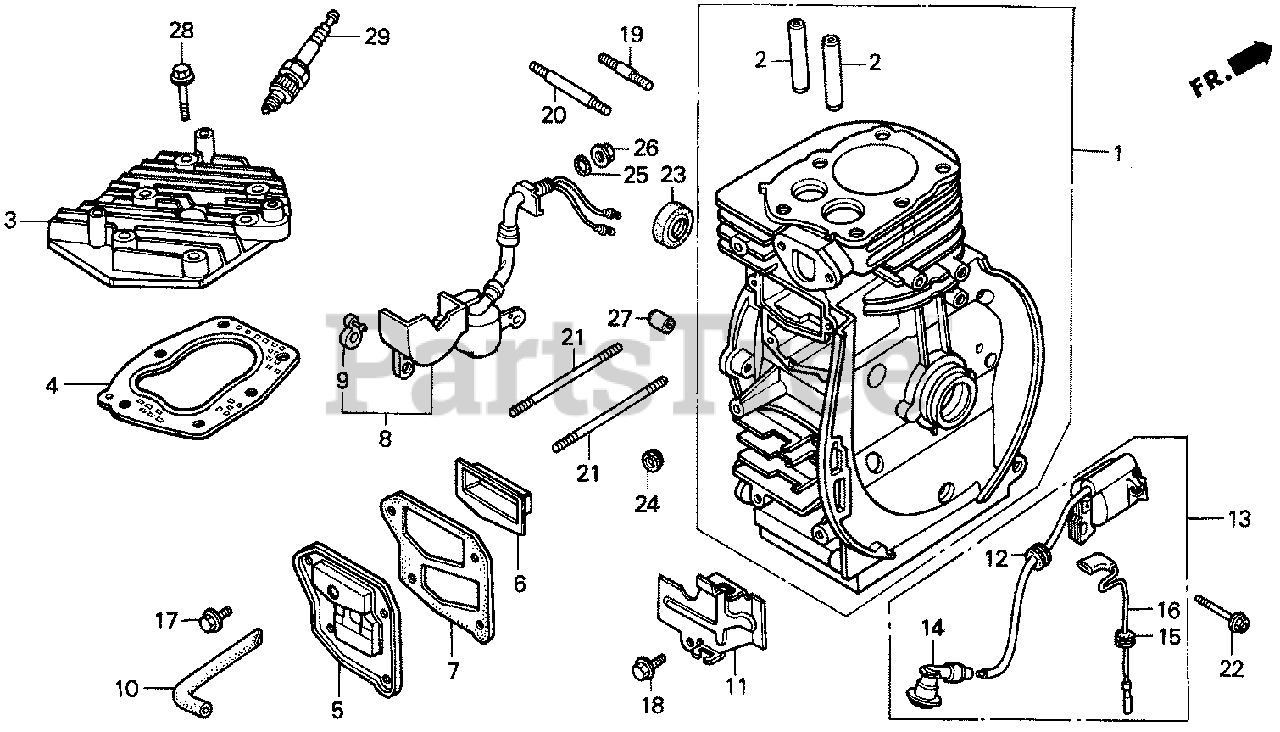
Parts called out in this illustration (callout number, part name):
1	CYLINDER ASSY. (000)
2	GUIDE, VALVE (OVER SIZE)
2	GUIDE, VALVE (OVER SIZE) Use up to Engine SN 1175298.
3	CYLINDER HEAD
4	GASKET, CYLINDER HEAD
5	COVER, TAPPET ROOM
6	SEPARATOR (INNER)
7	GASKET, TAPPET COVER
8	SWITCH ASSY., OIL LEVEL (TOYO DENSO)
9	BUSH, LEVEL SWITCH
10	TUBE, BREATHER
11	HOLDER, TUBE
12	GROMMET, CORD
13	COIL ASSY., IGNITION
14	CAP ASSY., NOISE SUPPRESSOR
15	GROMMET, SWITCH WIRE
16	WIRE, STOP SWITCH
17	BOLT, FLANGE (5X10)
18	BOLT, FLANGE (6X12) (CT200)
19	BOLT, STUD (6X32)
20	BOLT, STUD (6X63)
21	BOLT, STUD (5X85)
22	BOLT, FLANGE (6X25) (CT200)
23	OIL SEAL (17X30X6) (NOK)
24	OIL SEAL (5X10X4)
25	O-RING (14MM) (ARAI)
26	NUT, FLANGE (10MM)
27	PIN, DOWEL (8X14)
28	BOLT, FLANGE (6X35)
29	SPARK PLUG (BR-4HS) (NGK)
29	SPARK PLUG (W14FR-U)
